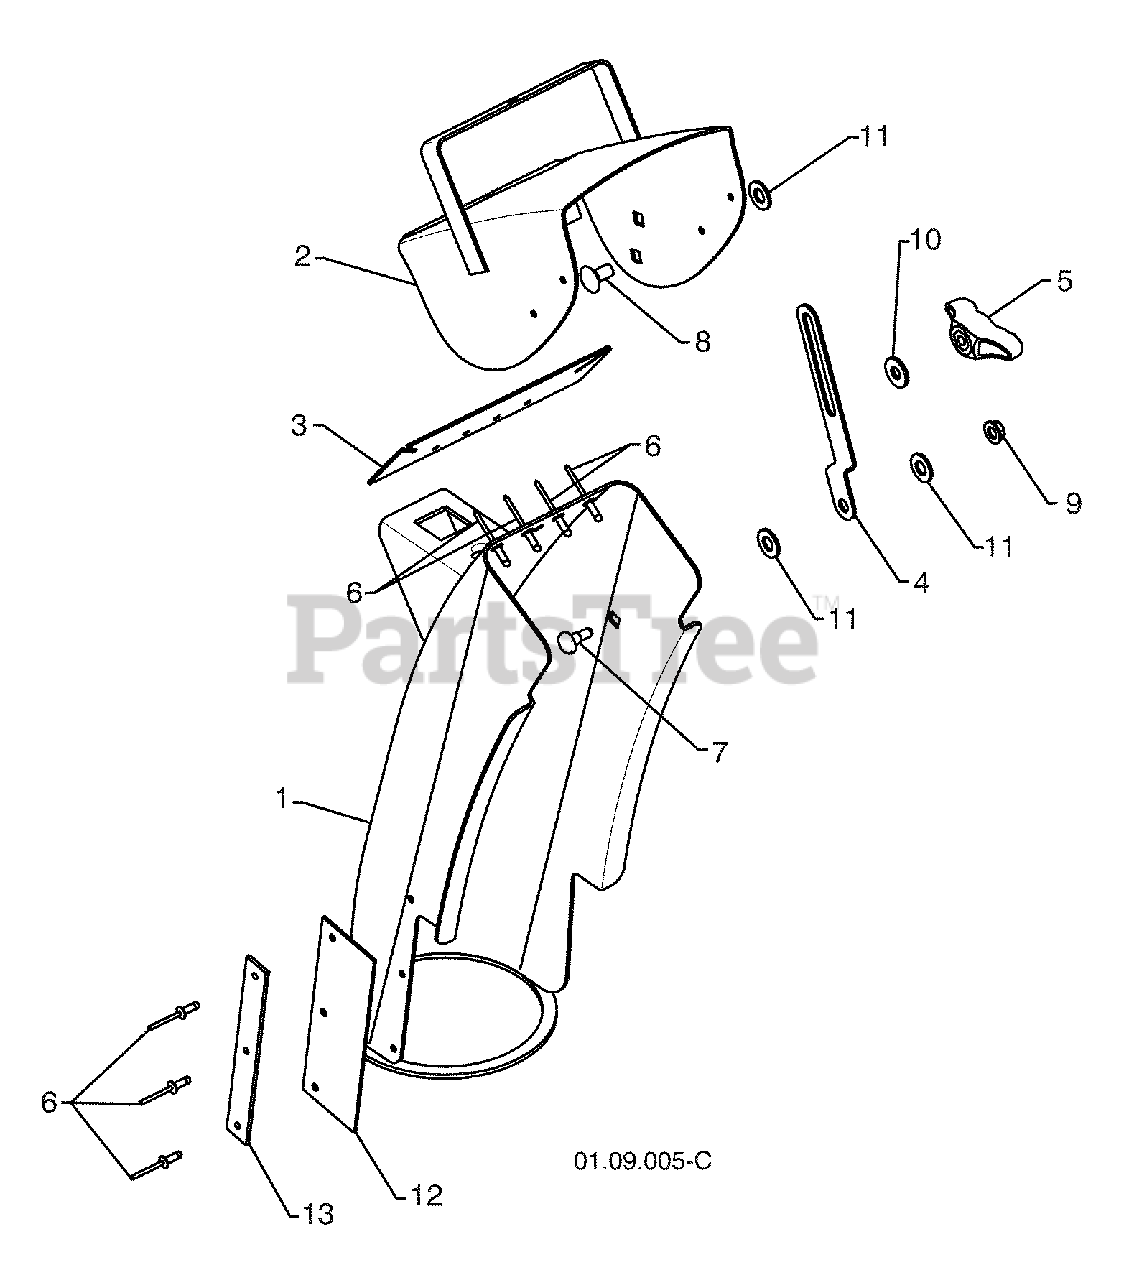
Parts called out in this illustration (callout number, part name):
1	CHUTE WELDMENT
2	DEFLECTOR WELDMENT
3	DEFLECTOR SEAL
4	STRAP
5	KNOB BLACK
7	SHOULDER BOLT 1/4-20 X .704
8	CARRIAGE BOLT 5/16-18 X .625
9	NUT 1/4-20
11	PLASTIC WASHER
12	CHUTE SNOW SHIELD
13	SHIELD RETAINER STRAP
